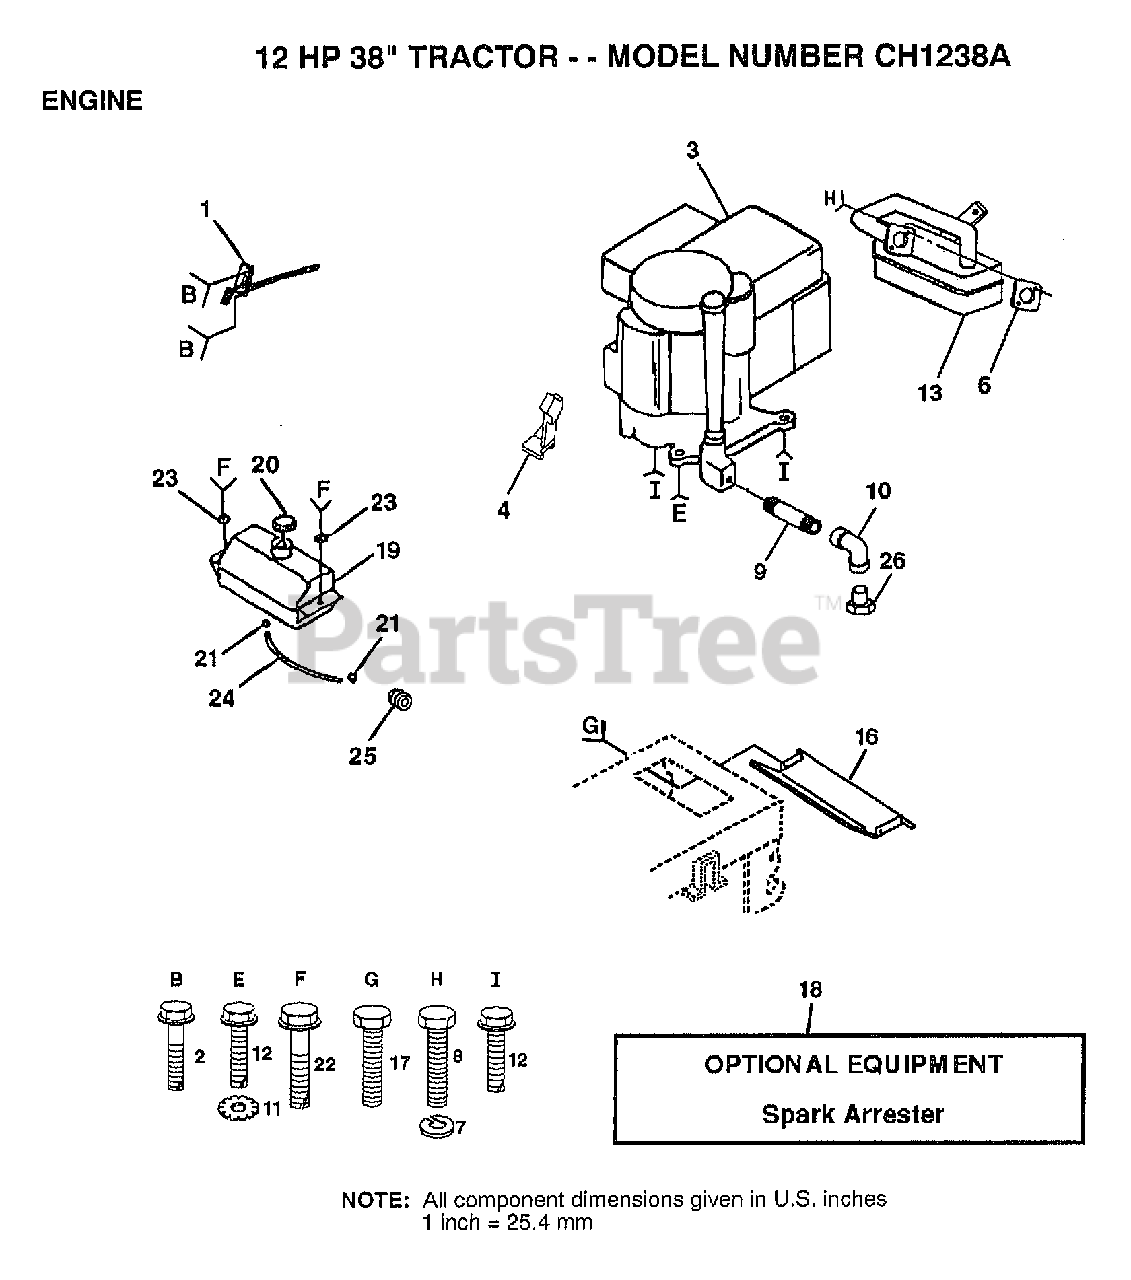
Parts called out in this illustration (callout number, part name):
2	SCREW LT
4	"STOP,DASH THROTT"
7	LOCKWASHER
8	SCREW
9	PIPE NIPPLE
10	ELBOW
11	LOCKWASHER
12	SCREW
13	MUFFLER
16	HEAT SHIELD
17	SCREW
19	TANK.FUEL.LT.
21	HOSE CLAMP
22	SCREW HEX CRT
23	WASHER
24	FUEL LINE T
